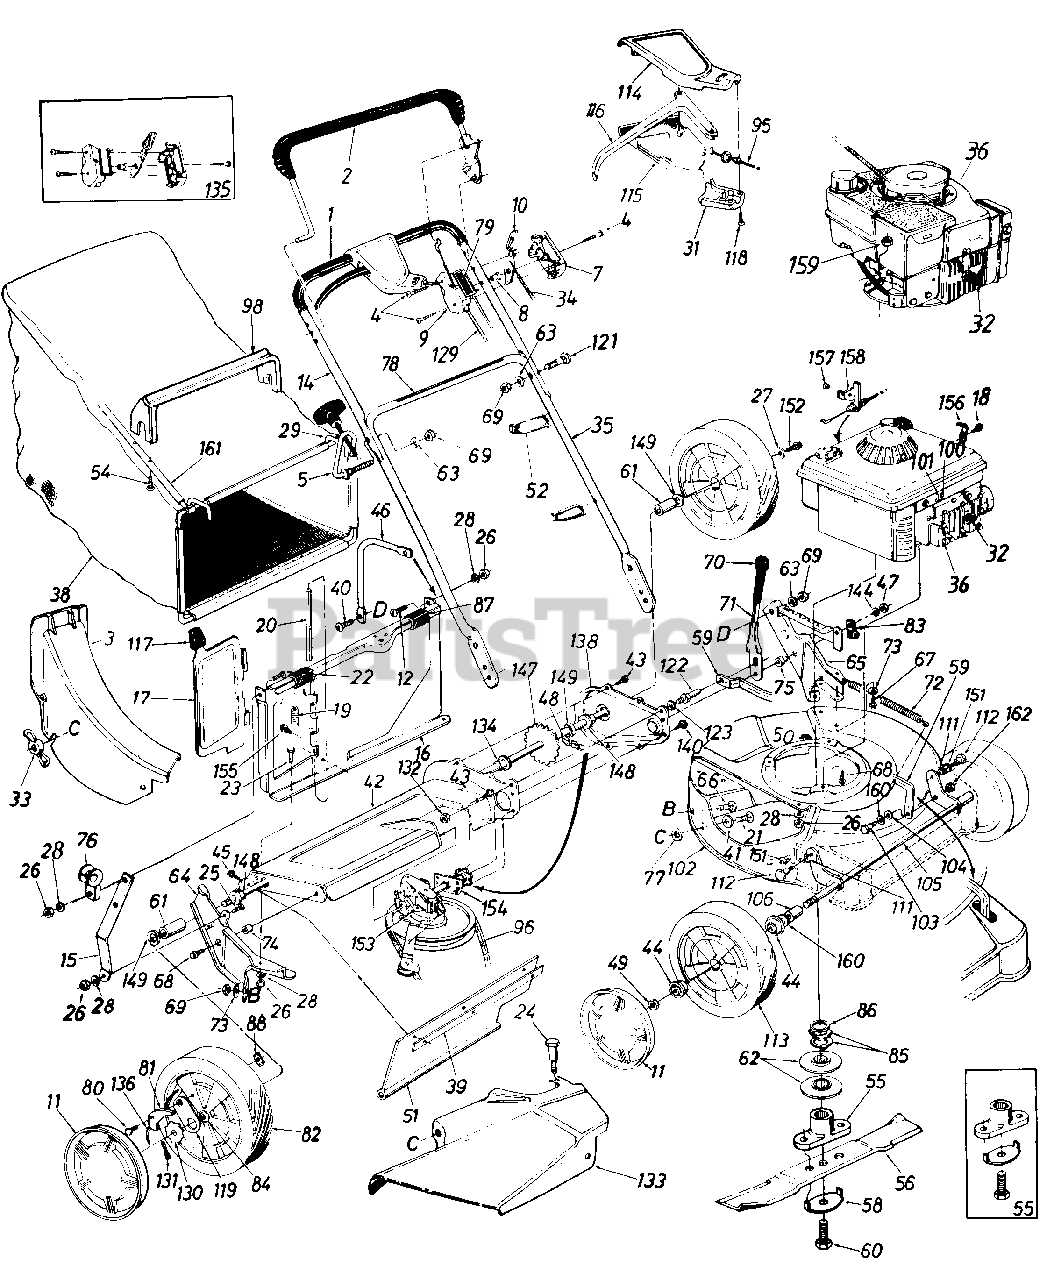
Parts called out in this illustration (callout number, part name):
1	Foam Grip
2	Control Handle Ass'y.-L.H.
3	Rear Discharge Chute Ass'y.
4	Truss Mach. Scr. #12 x 1.50" Lg.
5	Rope Guide Bolt
7	Control Panel Half
8	Control Disc Pin
9	Clutch Panel Half
10	Throttle Control Lever
11	Hub Cap
12	Truss Mach. Scr. 1/4-20 x .62" Lg.
14	Upper Handle-Painted
18	Hex B-Tap Scr. #10 x .38"
19	Torsion Spring
20	Pivot Pin
21	Carriage Bolt 1/4-20 x .62"
22	Truss Mach. Scr. 1/4-20 x 3/4 " Lg
23	Hex Bolt 1/4-20 x .50" Lg.*
24	Shoulder Bolt .312 Dia. x. .18 Lg.-Special
25	Hex Bolt 1/4-20 x .62" Lg.
26	Hex Nut 1/4-20 Thd.
27	Bell-Wash. 1/4" I.D.
28	L-Wash. 1/4" I.D.
31	S.P. Control Cover
32	Spark Plug Insulator
33	Wing Nut w/Washer
34	Throttle Control Wire 58"
35	Lower Handle-Painted
36	Engine
38	21" Rear Discharge Grass Bag-Black
39	Retaining Strip
40	Truss Mach. Scr. 5/16-18 x .75" Lg.
41	Fl-Wash. .344" I.D. x .62"
44	Flange Ball Bearing 1/2" I.D.
45	Hex AB-Tap Scr. 1/4 x .6211
46	Catcher Panel Support Arm
47	Hex Patch L-Nut 3/8-24 Thd.
48	#48 Chain .500" Pitch x 30 Links
49	Hex L-Nut 1/2-20 Thd.
51	Rear Flap 3.75" x 17.30 Lg.
52	Cable Tie
54	Hex AB-Tap Scr. 1.25" Lg.
55	Blade Adapter Kit
56	21" Blade
58	Blade Bell-Wash. .44" I.D. x 2.38"
59	Height Adj. Connecting Arm
60	Hex Bolt 7/16-20 x 1.5" Lg. (Grade 5)
61	Spacer .513" I.D. x .703" O.D. x .69" Lg.
62	Serrated Pulley Half
63	L-Wash. 5/16" I.D.
64	R.H. Handle Wheel Brkt. Ass'y.
65	L.H. Handle Wheel Brkt. Ass'y.
66	Carriage Bolt 5/16-18 x .62"
67	Hex Wash. Hd. B-Tap Scr. 5/1 6-1 8
68	Hex Wash. Hd. TT-Tap Scr. 3/8-1 6
69	Hex Nut 5/16-18 Thd.
71	Height Adj. Lever
72	Extension Spring .75" O.D. x 8" Lg.
73	Bell-Wash. 5/16" I.D.
74	Spacer
75	Shld. Spacer .500" Dia.
76	Rope Guide
77	Bolt Retainer 1/4 x .50" O.D.
78	Instruction Label
79	Control Label
80	Shld. Scr. .342" Dia. x .268
81	Pawl
82	Wheel Ass'y. Comp.
83	Clamp
84	Bearing 1/2" I.D.
85	Wave Washer 1.005" I.D.
86	Serrated Washer 1.0" I.D.
87	Panel Clip
88	Flat Weld Nut 1/4-20 Thd.
95	S.P. Cable-48" Lg.
96	"V"-Belt
98	Bag Handle (Black)
100	Hex B-Tap Scr. #10 x .62"
101	Cable Clamp
102	629/N 21" Deck Ass'y.
103	Shld. Bolt .5" Dia. x .295
104	Bell-Wash. .515" I.D. x 1.0" O.D.
105	Front Axle Ass'y.
106	Sleeve .526" I.D. x .690" O.D. x .880" Lg.
111	Intern. L-Wash. 3/8 I.D.
112	Shld. Bolt .575" Dia. x .42
113	Wheel Ass'y. Comp.
114	Self-Propelled Control Cover
115	Self-Propelled Control Cover
116	Control Lever
117	Door Grip
118	Fl-"C"-Sunk Hd. Tap Scr. #10 x .75" Lg.
119	Pawl Plate
121	Curved Carr. Bolt 5/16-18 x 1.38" Lg.
122	Shld. Pin 3/8-24 x 1.43" Lg.
123	L-Wash. 3/8" I.D.
129	Control Cable 58" Lg.
130	Ratchet Wheel 1.62" O.D.
131	Cotter Pin 1/8" Dia. x 1.00" Lg.
132	Hex Jam Nut 3/8-24 Thd.
133	Side Chute Deflector Ass'y.
134	Hex Flange Bearing
135	Kit-Control Housing Comp.
136	Spring-Nylon
144	Fl-Wash. .385" I.D. x .87"
147	Rear Shaft Ass'y. 21.94" Lg.
148	Hex Flange Bearing .506" I.D. Plastic
149	Fl-Wash. .531" I.D. x .930"
151	Flanged Nyliner Brg.
152	Hex Bolt 1/4-20 x .62" Lg. (Grade 5)
153	Transmission Comp.
154	Hex Bearing Cup
155	Hex B-Tap Scr. #10 x .38t
156	Cable Clamp
157	Pop Rivet .156" Dia.
158	Cable Bracket
159	Hex Nut 3/8-16 Thd.
160	Fl-Wash. .51" I.D. x .75" O.D.
162	Elex Jam Nut 3/8-16 Thd.
